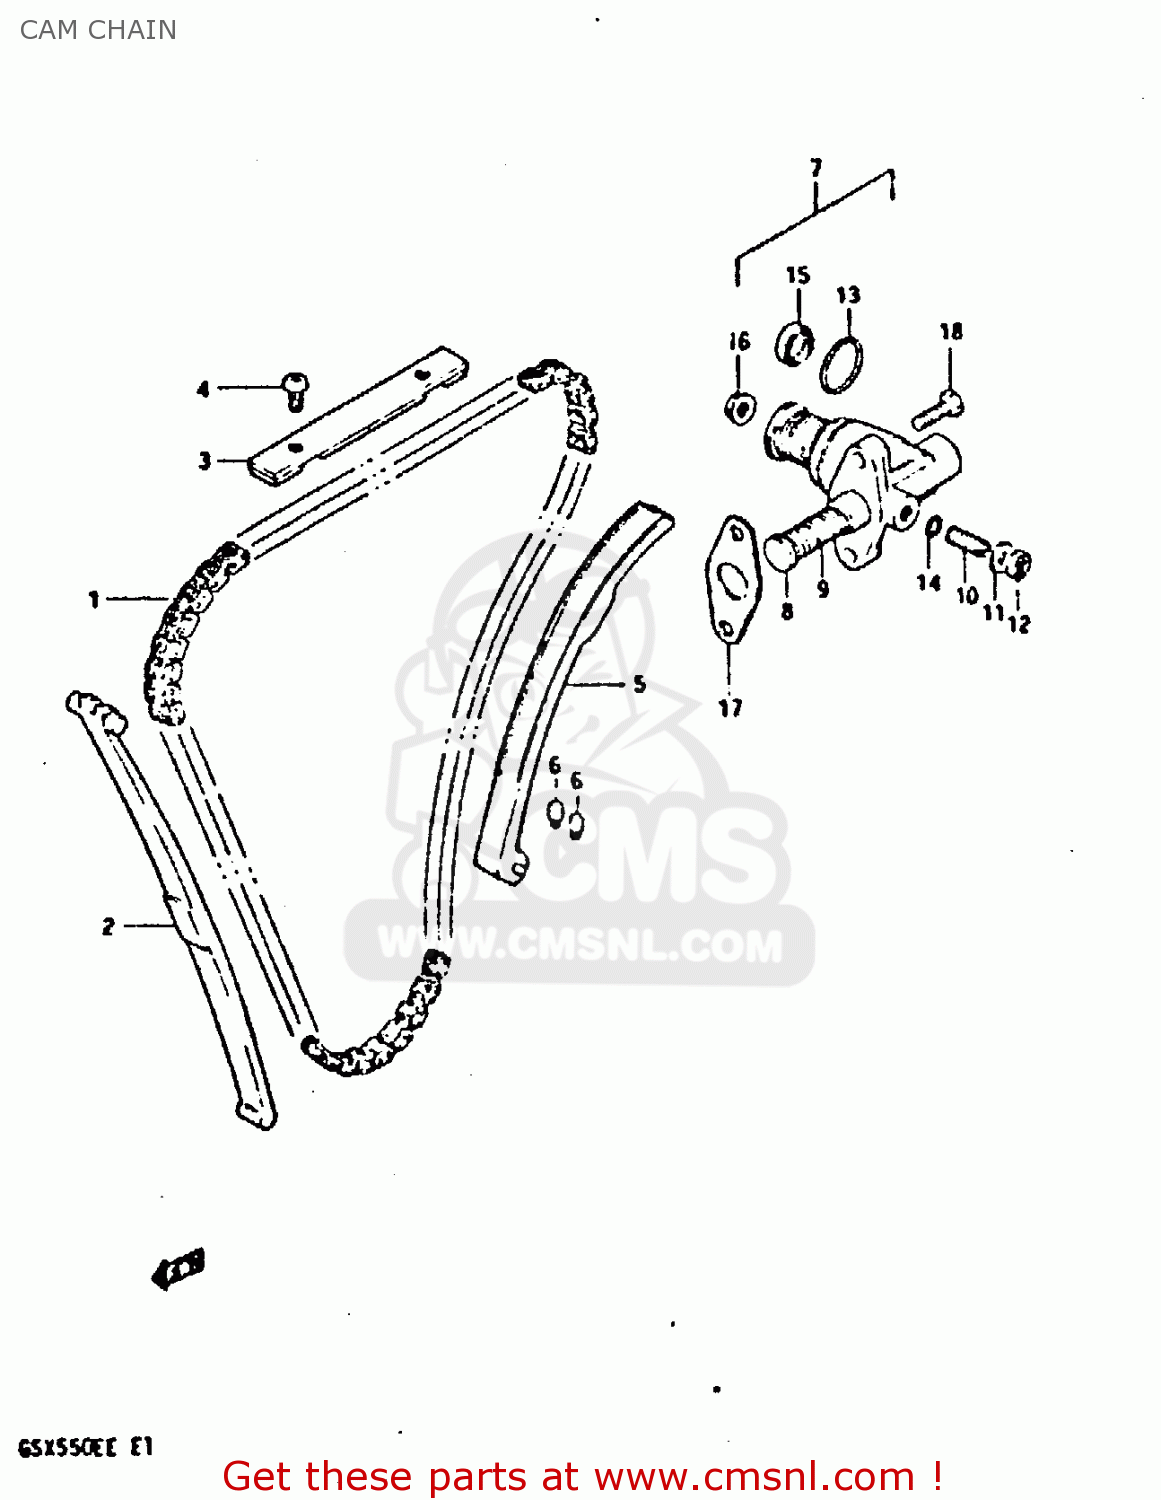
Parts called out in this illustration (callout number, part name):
1	CHAIN,CAMSHAFT DRIVE
2	GUIDE,CAM CHAIN NO.1
3	GUIDE,CAM CHAIN NO.2
4	SCREW
5	TENSIONER,CAM CHAIN
6	CUSHION,CAM CHAIN TENSIONER
7	ADJUSTER ASSY,TENSIONER
8	PUSH ROD
9	SPRING
10	SCREW,TENSIONER ADJUST
11	WASHER,8.5X16X
12	NUT
13	O RING(D:2.4,ID:20.8)
14	O RING(D:1.9,ID:5.7)
15	SEAL,OIL(10X16X4)
16	NUT
17	GASKET,TENSIONER ADJUSTER (MCA)
18	SCREW
